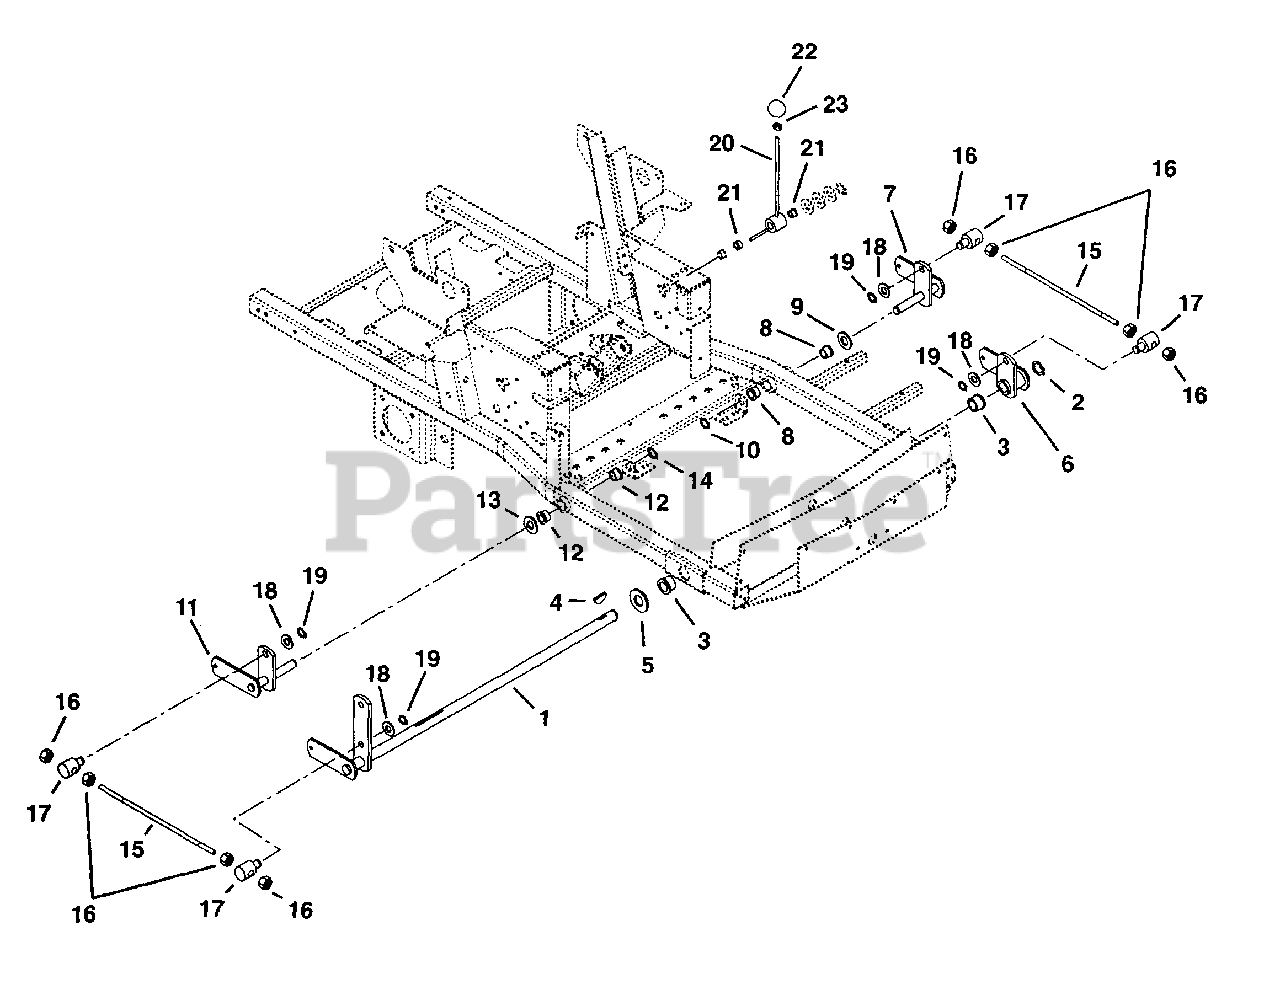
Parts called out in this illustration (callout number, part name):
1	Lift-Mower
2	Ring-Retaining-External 1.00 x .078
3	Bushing-Flange-Nylon 1.020 x 1.385 x .75 x 1.75
4	Key-Woodruff .25 x 1.00
5	Washer-Flat-Steel 1.063 x 2.00 x .134
6	Weldment, Lift Arm-Front
7	Weldment, Lift Arm-Shaft-Left Hand
8	Bushing-Flange-Nylon .762 x 1.0 x .580 x 1.48
9	Washer-Hardened-Steel .758 x 1.23 x .031
10	Ring-Retaining-External .689 x .077
11	Weldment, Lift Arm Shaft-Right Hand
12	Bushing-Flange-Nylon .762 x 1.0 x .580 x 1.48
13	Washer-Hardened-Steel .755 x 1.23 x .031
14	Ring-Retaining-External .689 x .077
15	Rod-Lift Assist
16	Nut-Hex .50-13
17	Pivot-Mower Lift
18	Washer-Flat-Steel .630 x 1.005 x .062
19	Ring-Retaining-External .625 x 050
20	Lever-Deck Lift
21	Bushing-Flange .630 x 1.000 x .625
22	Knob-Steering Lock
23	Nut-Hex-Jam .375 -16
